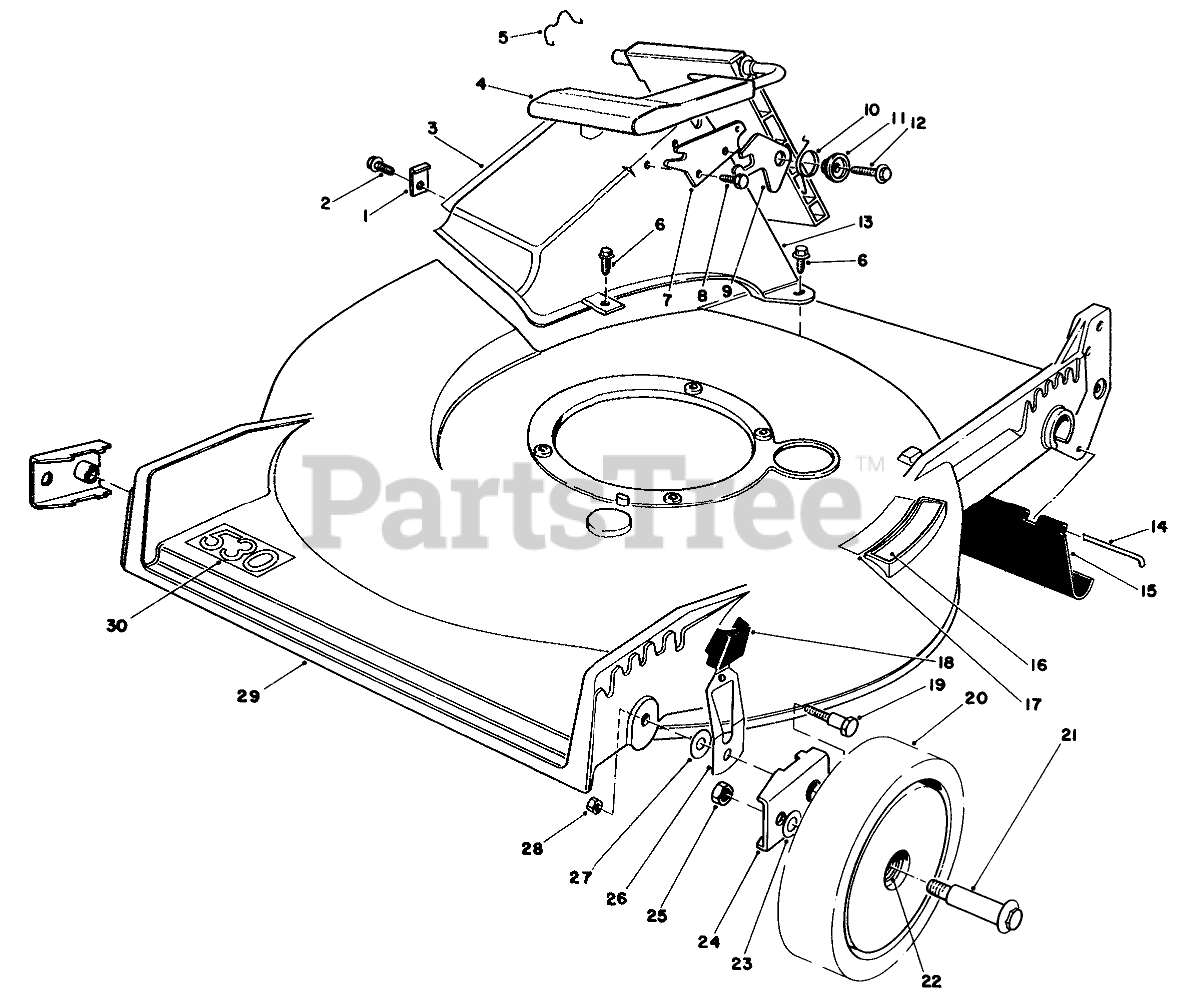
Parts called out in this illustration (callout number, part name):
1	TUNNEL CLIP
2	SCREW
3	Decal-Attention
4	Discharge Door Assembly
5	DOOR RET SPRING
6	SCREW-HWH
7	DOOR LATCH PLATE
8	SCREW-PLASTITE
9	SAFETY LATCH
10	TORSION SPRING
11	DOOR SPACER
12	SCREW-HWH
13	Tunnel Discharge
14	ROD-SHIELD
15	SHIELD-TRAILING
16	STEP PAD DECAL
17	Decal-Place Foot Here
18	KNOB-ARM
19	PIVOT SCREW
20	Wheel & Tire Assembly (Incl. Ref. #22)
21	WHEEL BOLT
22	BUSHING
23	WASHER
24	HP PIVOT ARM ASM
25	NUT-LOCK
26	Spring Arm
27	WASHER-PIVOT
28	NUT-LOCK, NI
29	21HP RB-SUZ HSG/DECAL
30	Decal-530
